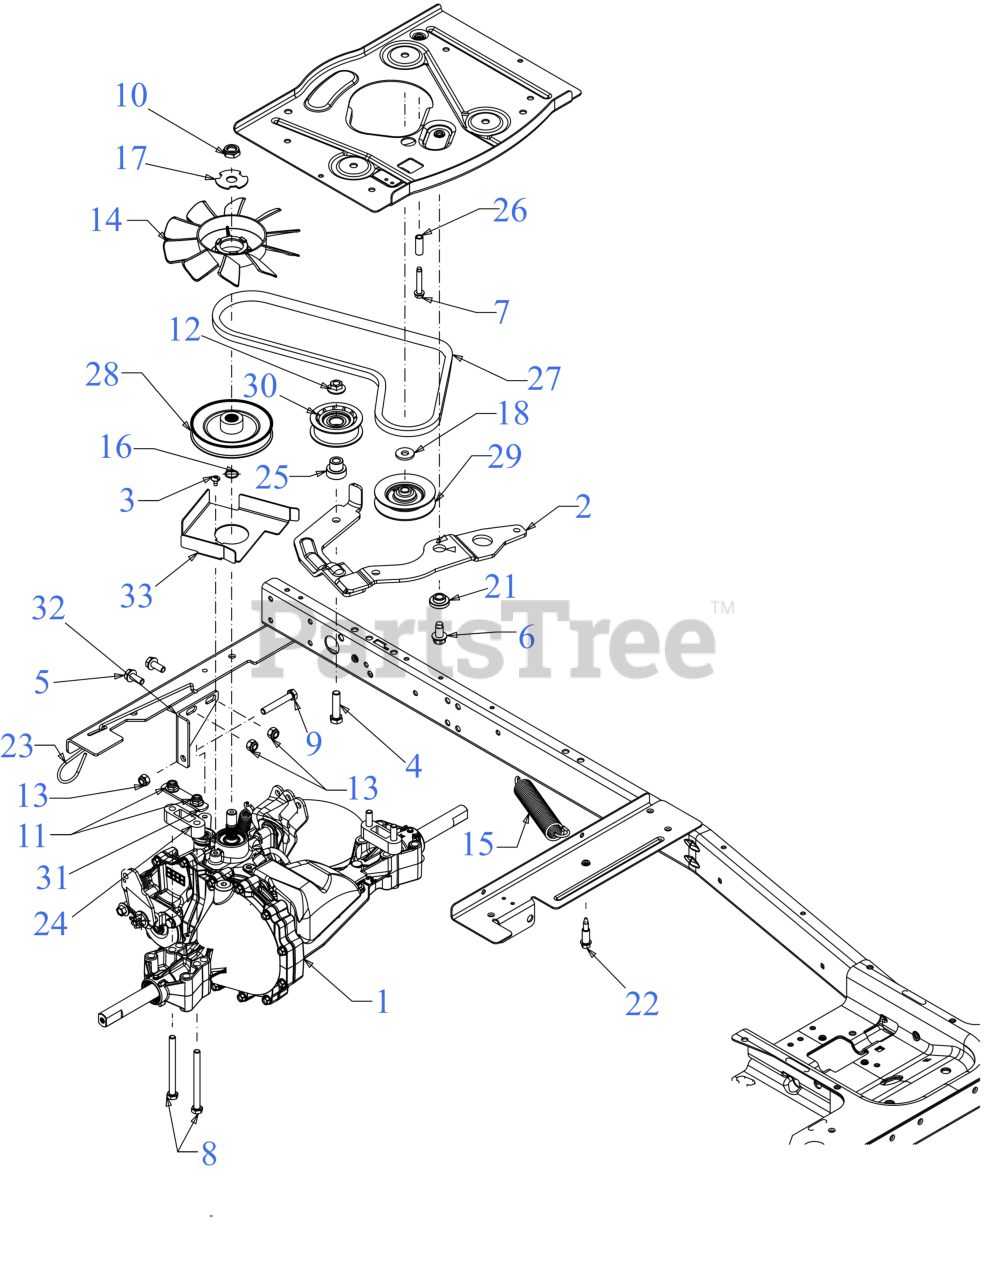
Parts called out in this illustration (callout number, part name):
1	TRANSMISSION ASSEMBLY
3	SCREW-#10-24 x .400 SELF TAP
4	SCREW 3/8-16 x 1.50
5	SCREW 5/16-18 x .750 GR8
6	SCREW 3/8-16 x 3/4
7	SCREW 1/4-20 x 1.50"
8	SCREW 5/16-18X3.5 GR5
9	SCREW 5/16-18 x 2.0 GR5
11	FLANGE LOCK NUT 5/16-18
12	FLANGE LOCK NUT
15	EXTENSION SPRING (.99 x 6.18)
16	WIRE RING
17	LOCK WASHER
21	SHOULDER SPACER 1.00 x .38 x .38
22	SHOULDER SCREW .368 x .75 x 1/4-20
23	HYDRO BYPASS ROD
24	TRANSAXLE SPACER
25	SHOULDER SPACER
27	V-BELT A SEC x 38.24"
27	Genuine Factory Parts TRANS BELT (754-05130)
28	INPUT PULLEY
29	V-IDLER PULLEY A x 3.06 OD
30	FLAT IDLER PULLEY
31	TRANSAXLE BRACKET
32	TRANSMISSION MOUNTING BRACKET
